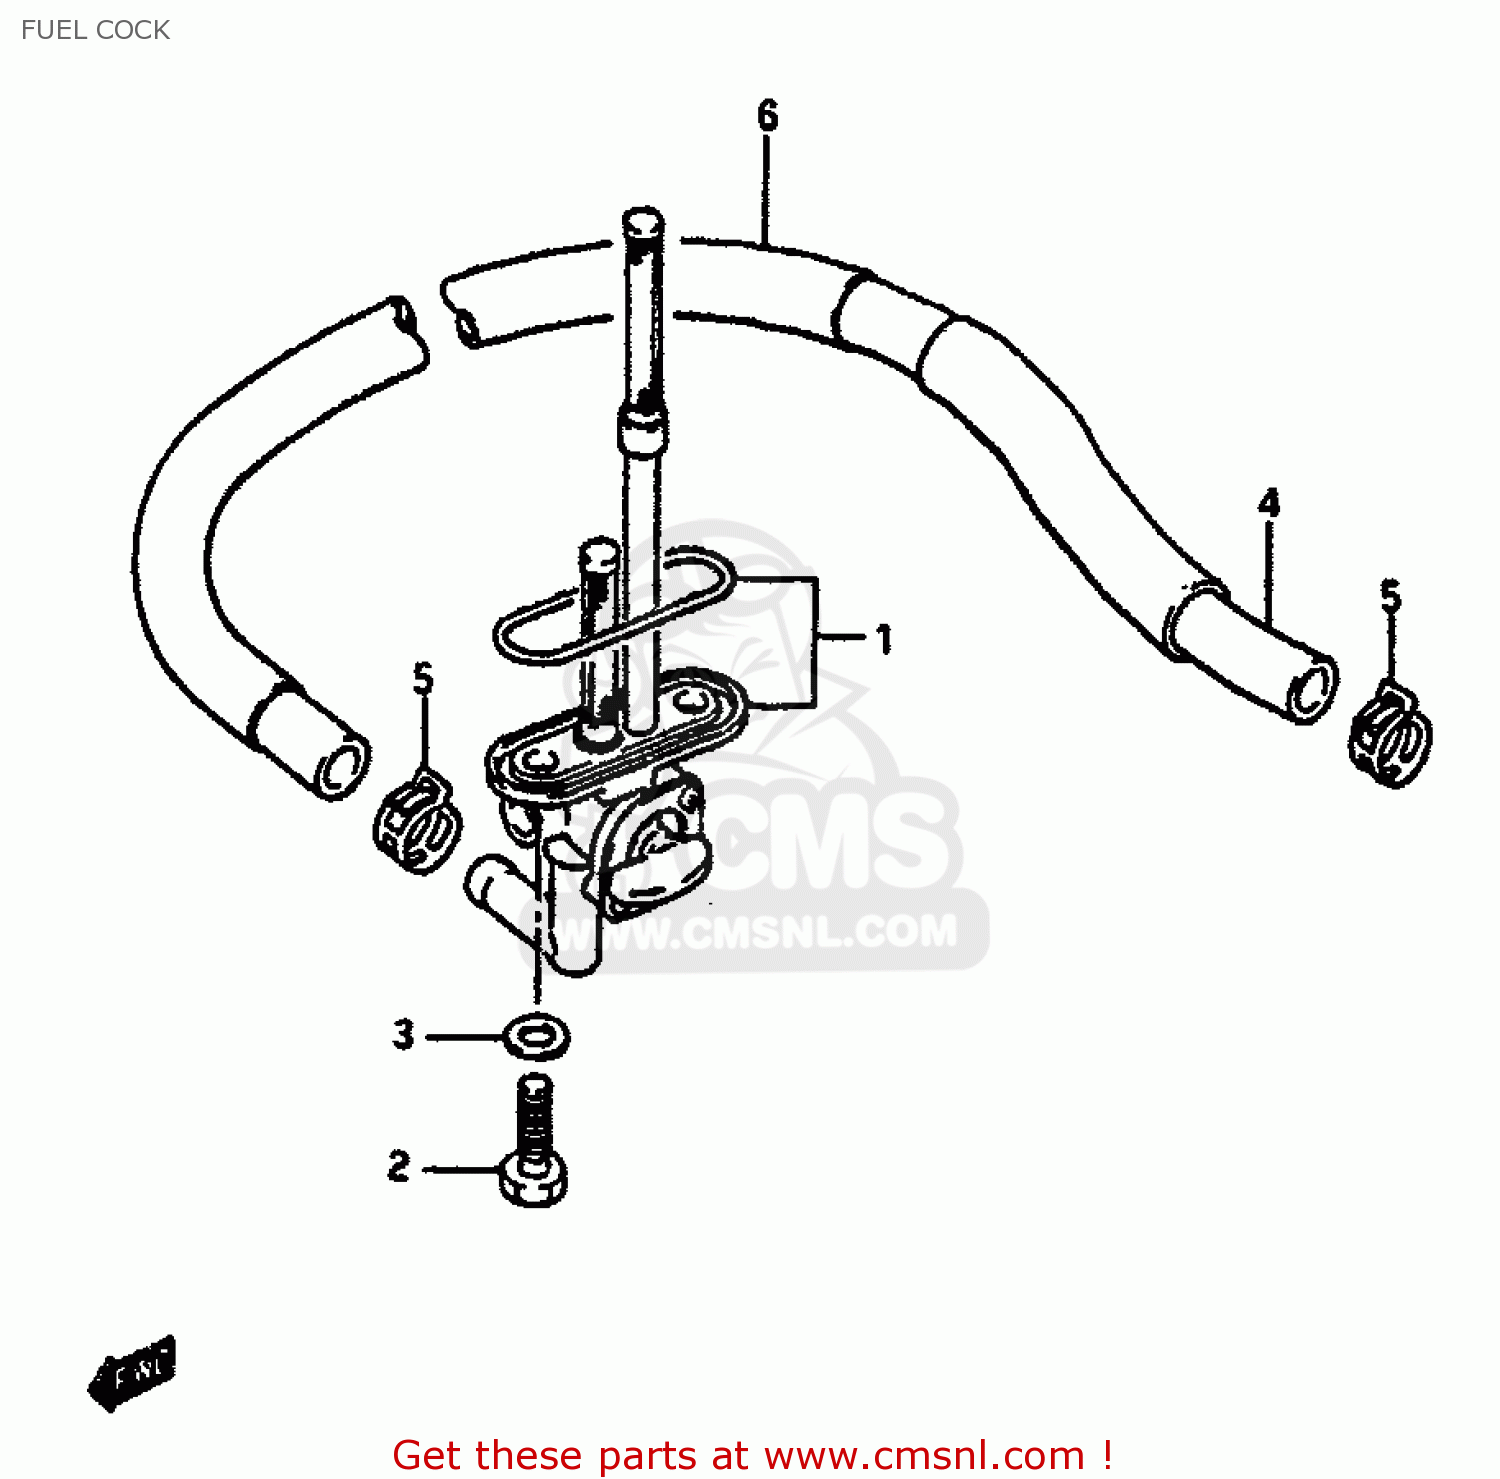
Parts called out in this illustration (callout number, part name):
1	COCK ASSEMBLY,FUEL
2	BOLT(6X20)
3	GASKET
4	HOSE,FUEL PUMP & COCK
5	CLAMP
6	TUBE,FUEL HOSE
